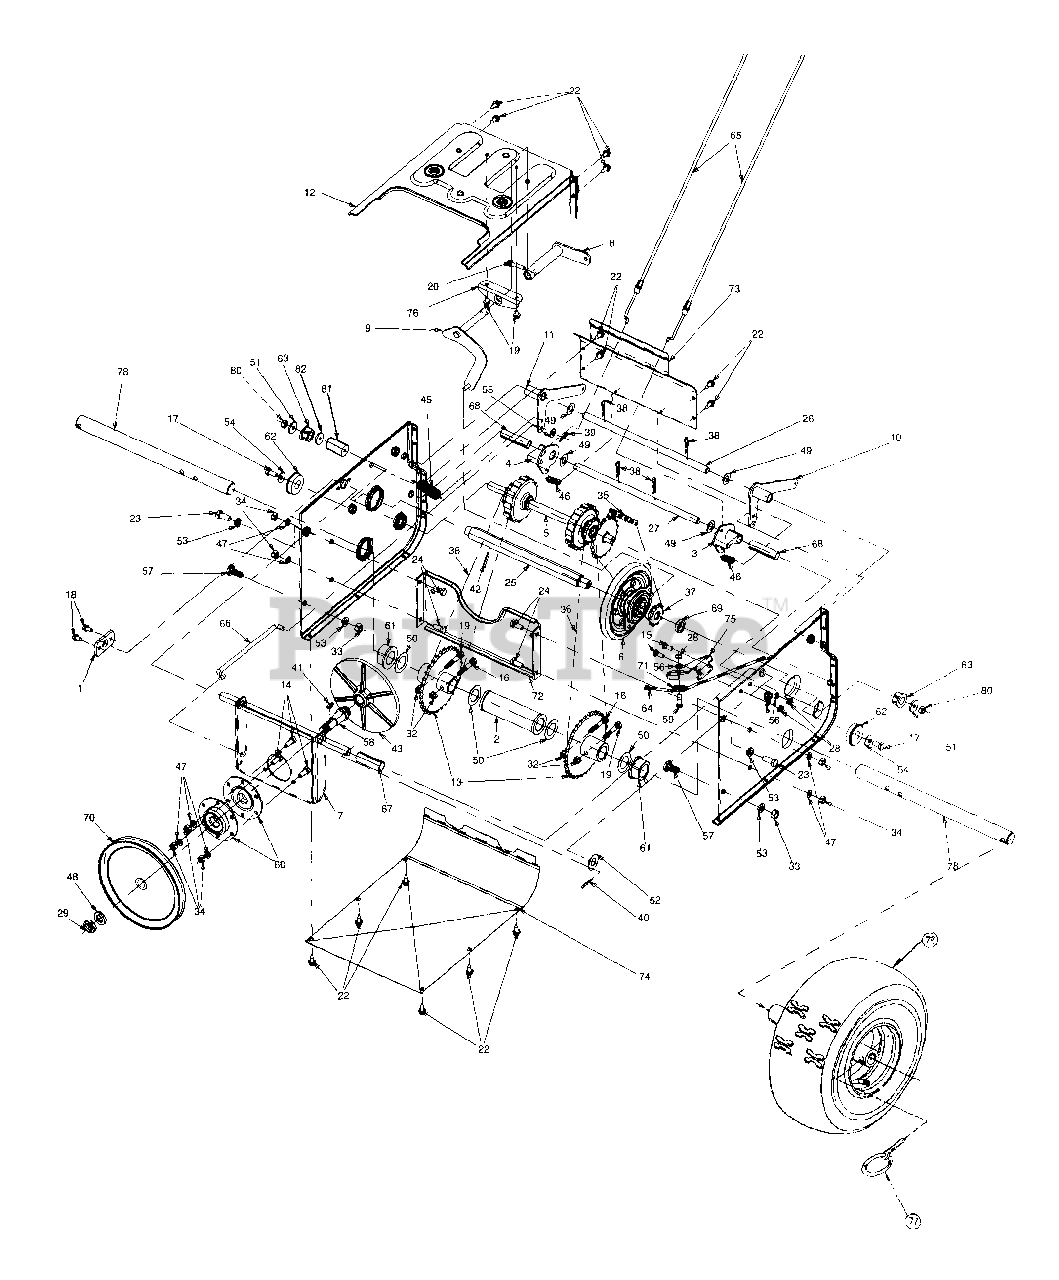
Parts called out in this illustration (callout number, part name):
1	Pivot Axle Brkt. .63 Hole - Zinc
2	Bush Asm slev
3	Dogg Asm Dr Lh
4	Dogg Asm Dr Rh
5	Shf Asm Dr
6	Whl Asm Brg 6.0 OD Friction
7	Brkt Asm Supt Friction Dr
10	Brkt Asm Actr Auger
11	Brkt Asm Actr Dr
14	Hex Scr 5/16-18 x .75
15	Hhcs 1/4-28 .625 Gr5 std
16	Hex Scr 5/16-18 x 2.00
17	Hhcs 5/16-18 x .625 Gr5 Lock
18	Scr TT 1/4-20 x .5 Hxindwsh
19	Hex Scr 5/16-18 2.00 Lg
20	Scr Hexwash 1/4-20 x 2.00
22	Scr Ab 1/4-20 .625 Hxindwsh
23	Hhcs 3/8-16 x .880 Gr5 Std
24	Scr Cap 5/16-18 x .75 Gr 5
25	Shf Dr .875 Hex
26	Shf Sctr
27	Shf Actr Dr
28	Hex Nut 1/4-28
29	Hex Ins Jam L-nut 5/8-18
32	Hex Ins L-nut 5/16-18
33	Hex Nut 3/8-16
34	Nut Hex 5/16-18 Gd 5
35	#41 Chain 1/2 Pitch x 36 L
36	#420 Chain 1/2 Pitch x 40 L
37	Spkt 10t #41 x .500
38	Internal Cot-pin 1/2 Dia.
39	Intern Cot-pin 5/16 Dia.
40	Cotter Pin 1/8 Dia. x 1
41	#61 Hi-pro-key 3/16 x 5/8
42	Spring Pin Roll 5/32
43	Aluminum Drive Plate
45	Idler Extension Spring
46	Extension Spring
47	Lock Washer 5/16
48	Lock Washer 5/8
49	Wash Fl .531 ID x .930 OD x .05
50	Wash Fl 1.03 ID x 1.62 OD
51	Wash Flt 1/4 ID x .930 OD x .12
52	Wash Flt .640 ID x 1.24 OD x .06
53	Lock Washer 3/8 Heavy
54	Bell Wash .345 ID x .88 OD
55	Fl-wash Sae .34 x .68 .062
56	Lock Washer 1/4
57	Shld Scr .498 Dia. x .340
58	Drive Plate Spindle
59	Scr Shldr .340 D. 1/4 Ab
60	Asm Brg Hsg
61	Flange Brg Pm W/flts 1.0
62	Ball Bearing W/snap Ring
63	Brg Hex Flange x .564 ID
64	Cb Idlr Auger
65	Cbl Strg
66	Rod Clu Dr
67	Spcr Spit .64 x .77 x 2.1
68	Split Spacer 1/2 x 5/8 x 2.44
69	Spcr .675 ID x 1.00 OD x .23
70	1/2 V-pulley .62 ID x 7.5
71	Cable Guide Roller
72	Brkt Supt Frm
77	Klik Pin Assy Danuse
78	Axle 1.0 OD x 14.1 Lg
80	Jam L-Nut 3/8-24 Thd.
81	Spacer
82	Fl-Washer
